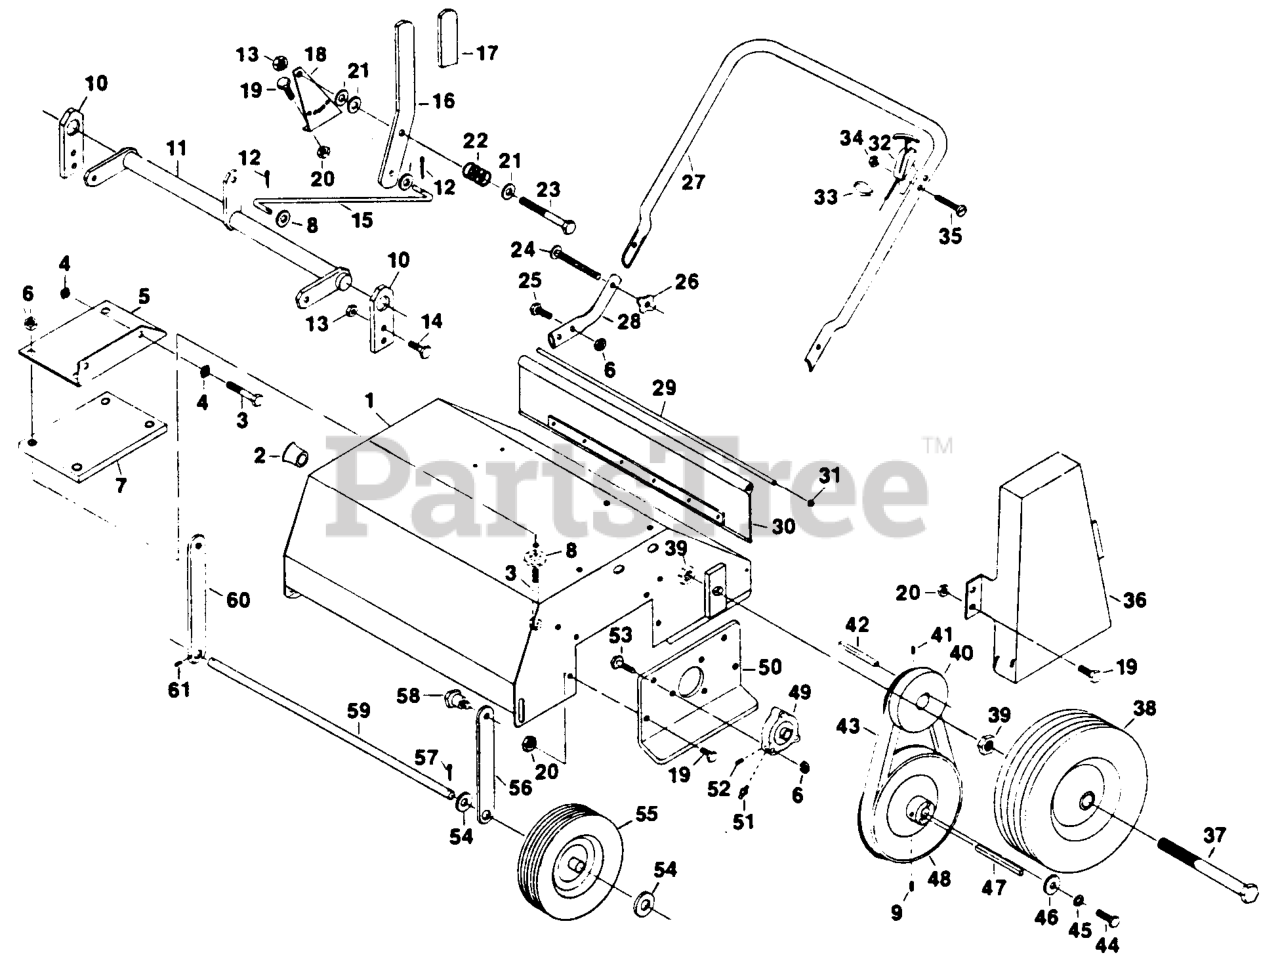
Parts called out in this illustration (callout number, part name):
9	SCREW-SET
12	PIN-COTTER
17	GRIP-LEVER
22	SPRING-COMPRESSION
31	NUT-PUSH
38	ASM,WHEEL & TIRE
43	BELT,RAKE
45	WASHER-LOCK
46	WASHER-RETAINER, PULLEY
55	ASM,WHEEL & TIRE
